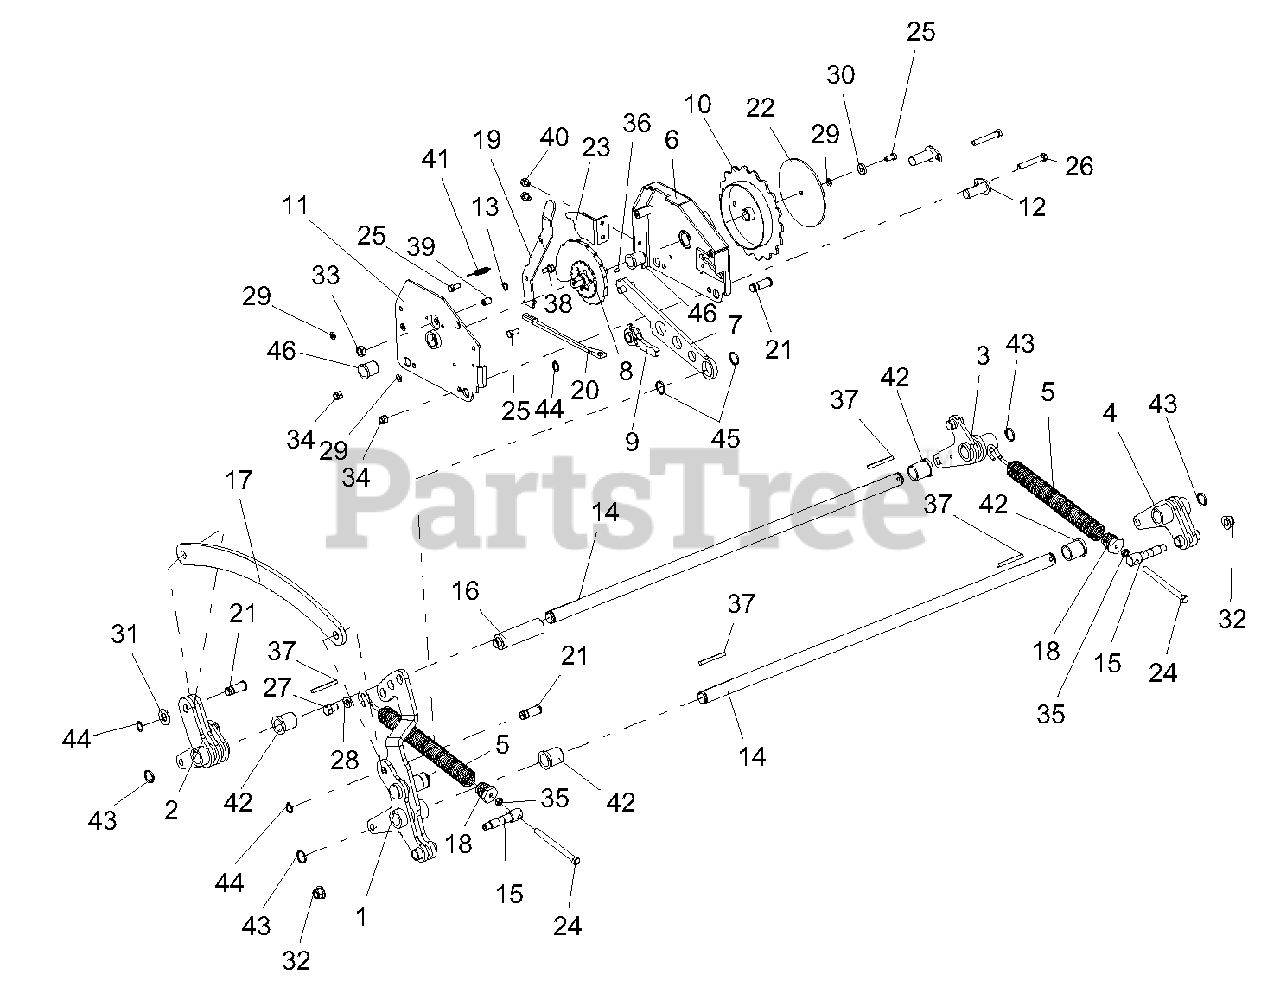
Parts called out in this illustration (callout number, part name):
1	WLDMT, LIFT PEDAL
2	WLDMT, LIF T
3	WLDMT, LIF T
4	WLDMT, LIF T
5	SPRG, DECK LIFT
6	WLDMT, HOC INNER
7	WLDMT, LINK
8	WLDMT, CAM HOC
9	WLDMT, LOCK PAWL
10	WLDMT, DIAL, HOC
11	WLDMT, HOC OUTER
12	WLDMT, PIN
13	WAVE, WASHER
14	SHAFT, FRONT MOWER LIFT
15	TRUNION, SPRG
16	PEDAL, LIFT
17	LIFT, LINK
18	PLUG, SPRG
19	LEVER, TRANSPORT LOCK
20	LINK, TRANSPORT LOCK
21	PIN, CLEVIS .625 SNAP RING
22	PLATE, DIAL-A-CUT
23	GUARD, DECK LIFT
24	BLT-HEX .38-16X5.0 GR5 FTD YWZ
25	BLT-HEX .31-18X.75 GR5 YWZC
26	BLT-HEX .38-16X2.50 GR5 YWZC
27	BLT-HEX .50-13X.75 GR5 YWZC
28	WSHR-LK .50X.125 REG YWZC
29	WSHR-LK .31X.078 REG YWZC
30	WSHR-FL-STL .328X.87X.179 YWZC
31	WSHR-FL-STL.656X1.31X.095 YWZ
32	NUT-LK-NYL-FLG .50-13 YWZC
33	NUT, 1/2-13 JAM GR5 y
34	NUT-LK-NYL .38-16 YWZC
35	NUT, 3/8-16 JAM GR5 Y
36	KEY-SQ .188X.188X.375
37	KEY-SQ .25 X 2.50 X .25 SAE
38	BOLT, SHLDR .38-16 x .437 HEX YZ
39	BALL SPRING PLUNGER, .500-13
40	SCR-TAP .31-18X.50 HWH TR YWZ
41	SPRING, EXT
42	BUSHING-FLANGE 1.00X1.25X1.50
43	RING-RETAINING-EXTERNAL 1.00X.078
44	RING-RETAINING-EXTERNAL .625X.050
45	RING-RETAINING-EXTERNAL 1.25X.050
46	BUSHING, .750 X 1.00 X .750
